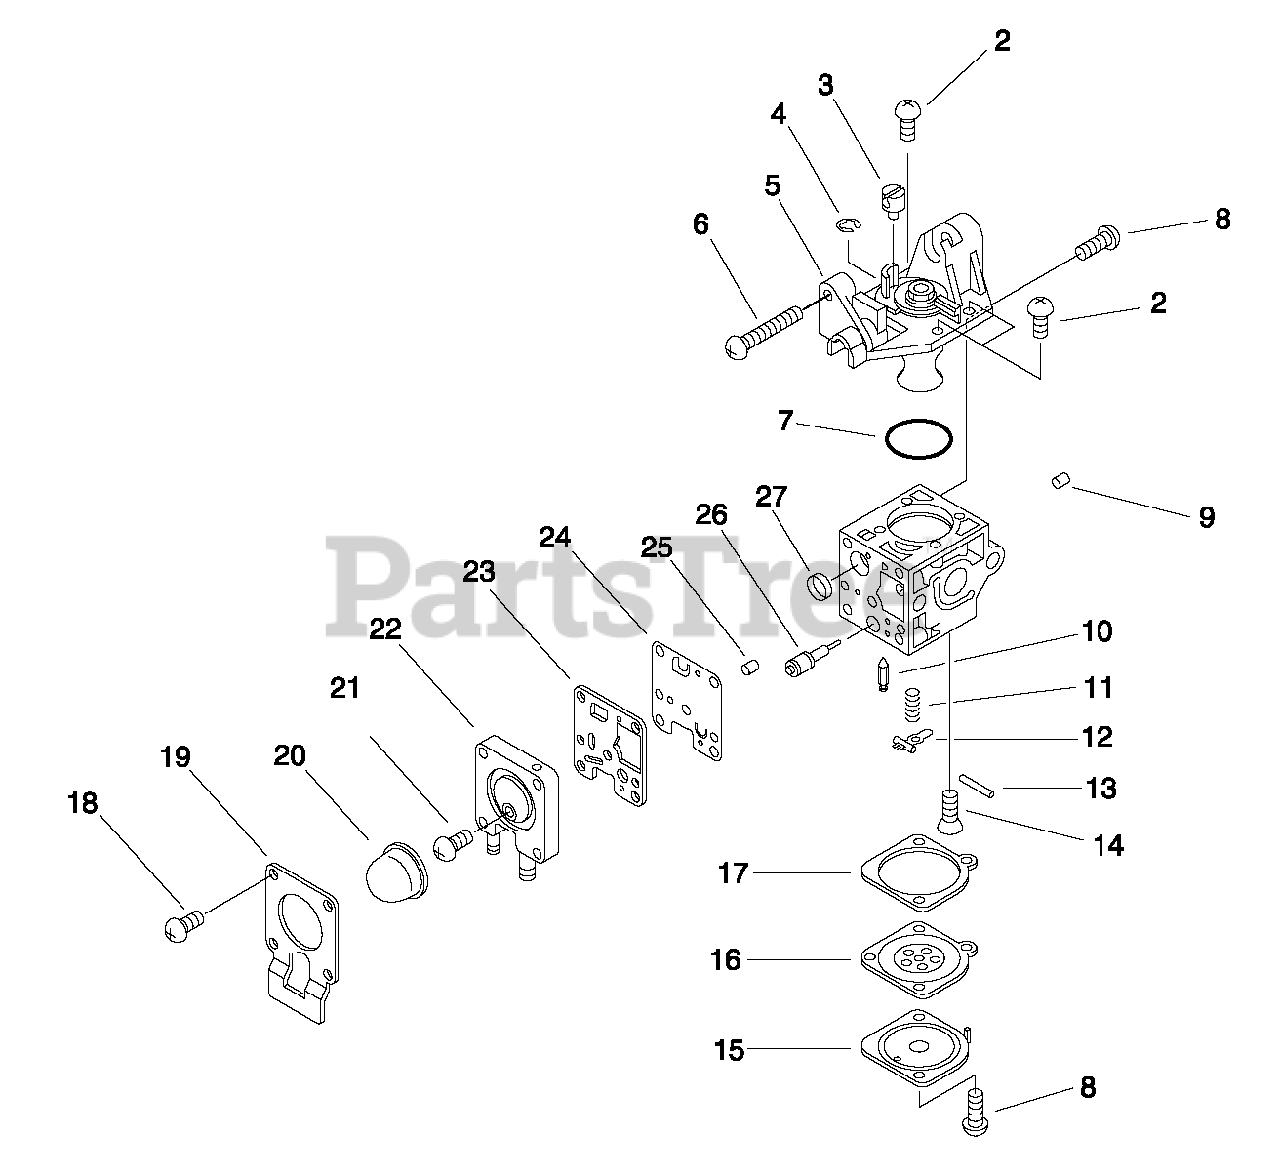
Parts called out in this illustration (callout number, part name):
1	CARBURETOR RB-K117 NO CAP
5	COVER ASSY, ROTOR
6	SCREW, IDLE ADJUST
9	GUIDE, ROLLER
10	VALVE, INLET NEEDLE
11	SPRING, METERING LEVER
12	LEVER, METERING
13	PIN, METERING LEVER
15	COVER, METERING DIAPHRAGM
16	DIAPHRAGM, METERING
17	GASKET, METERING DIAPHRAGM
19	RETAINER, PURGE BULB
20	BULB, PURGE
22	BODY ASSY, PURGE
23	GASKET, PUMP
24	DIAPHRAGM, PUMP
25	CAP, LIMITER
26	NEEDLE, HIGH SPEED
27	SCREEN, FUEL INLET
